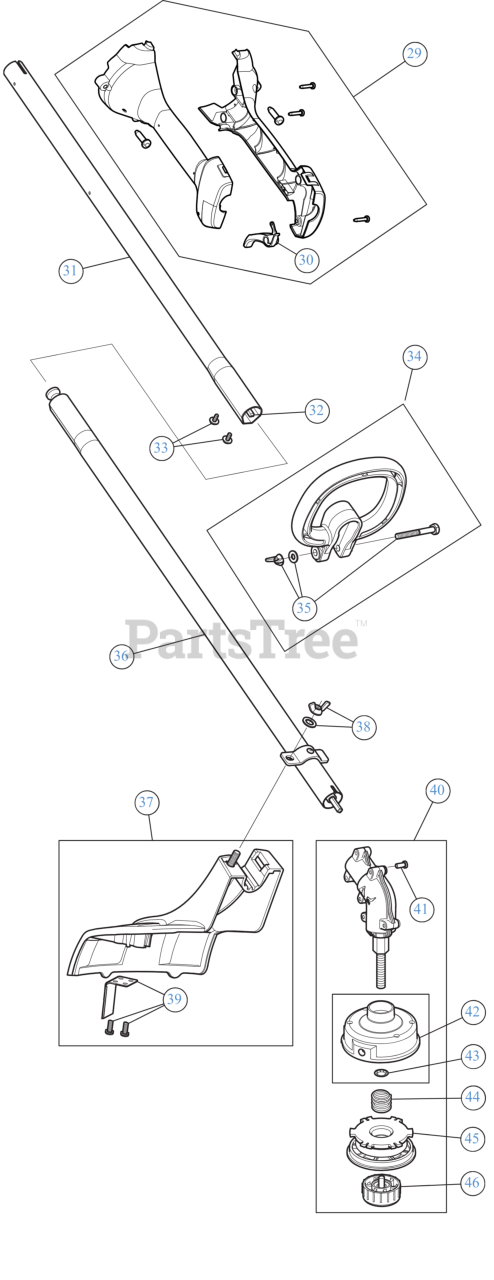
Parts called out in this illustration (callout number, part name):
29	THROTTLE GRIP ASSEMBLY
30	THROTTLE TRIGGER
31	UPPER BOOM ASSEMBLY
32	UPPER SHFT
33	SCREW 8-32X3/8
34	HANDLE
35	HANDLE HWD
36	LOWER BOOM ASSEMBLY
37	GUARD/BLADE ASM
38	BLADE GUARD MOUNTING HARDWARE
39	BLADE ASSEMBLY W/HDW
40	GEARBOX ASSEMBLY
41	SCREW 8-32X.437
42	REEL:OTR W/RET
43	RETAINER .625 OD 2
44	SPRING-SPOOL
45	REEL-INNER SPOOL
46	BUMP HEAD KNOB ASSEMBLY
